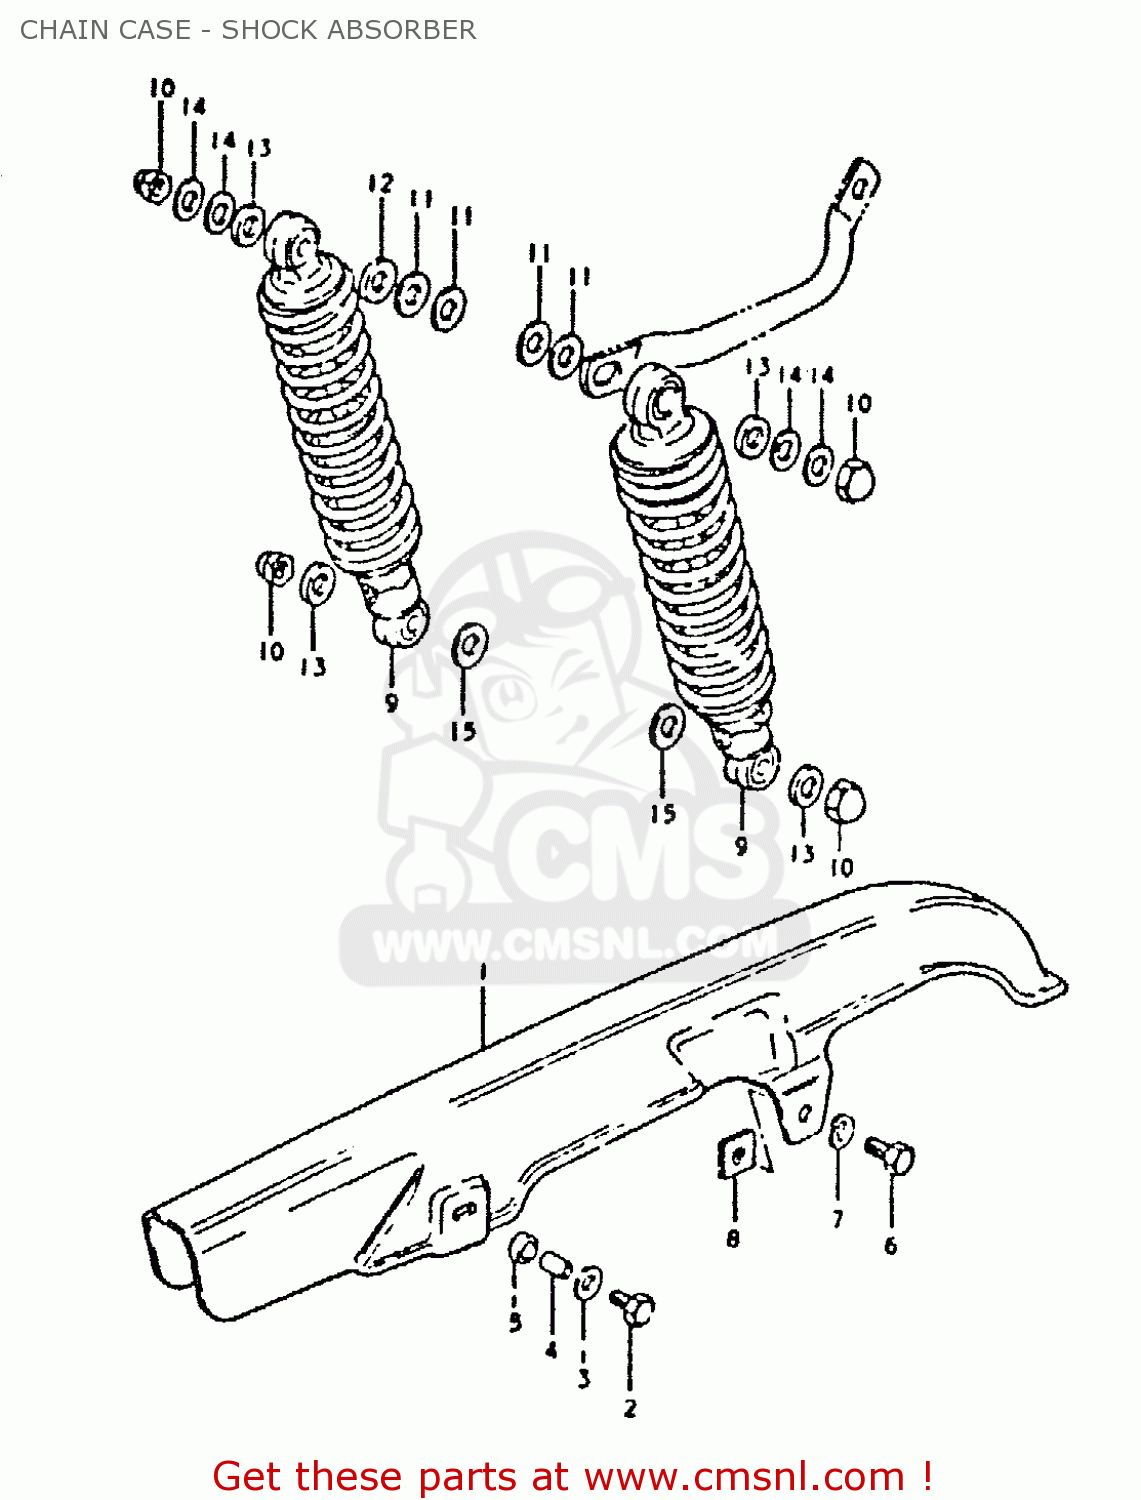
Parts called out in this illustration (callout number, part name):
1	CASE,CHAIN
2	BOLT
3	WASHER(6.5X18X1)
4	SPACER (6.1X8X5.2)
5	CUSHION
6	BOLT, UPPER
7	LOCK WASHER
8	NUT,CHAIN CASE RR
9	SHOCK ABSORBER, REAR
10	NUT, LOWER LH
11	WASHER
12	WASHER (12.5X24X3.2)
13	WASHER
14	WASHER, OUTER (10.5*24*3.2)
15	WASHER (12.5X24X1.6)
